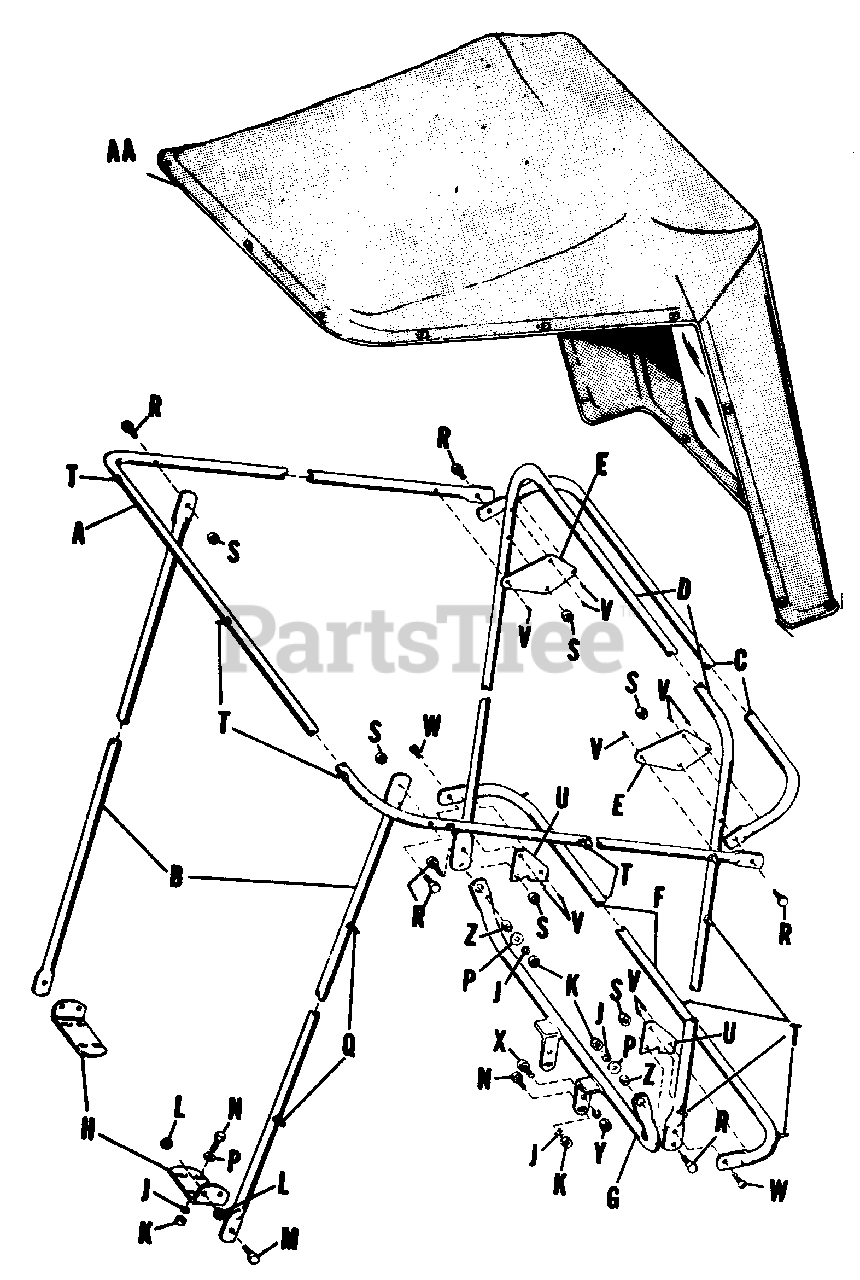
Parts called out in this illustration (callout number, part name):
A	Frame, Top Front
B	Brace, Side
C	Frame, Top Rear
D	Frame, Vertical
E	Gusset, Upper
F	Frame, Lower Rear
G	Tube, Rear Pivot
H	Bracket, Foot, Front
J	Lock Washer, 5/16"
K	Hex Nut, 5/16"-18
L	Hex Nut, 3/8"-16
M	Hex Capscrew, Drilled
N	Hex Capscrew, 5/16"-18 x 1" lg.
P	Washer, Plain, 5/16"
Q	Double Stud Lift-O-Dot
R	Hex Capscrew, 1/4"-20 x 1-3/4" lg.
S	Hex Lock Nut, 1/4-20
T	Single Stud Lift-O-Dot
U	Gusset, Lower
V	Screw, Self-Tapping, #10 x 1/2" lg.
W	Hex Capscrew, 5/16"-18 x 1-1/4
X	Hex Capscrew, 3/8"-16 x 1-1/4
Y	Hex Lock Nut, 3/8"-16
